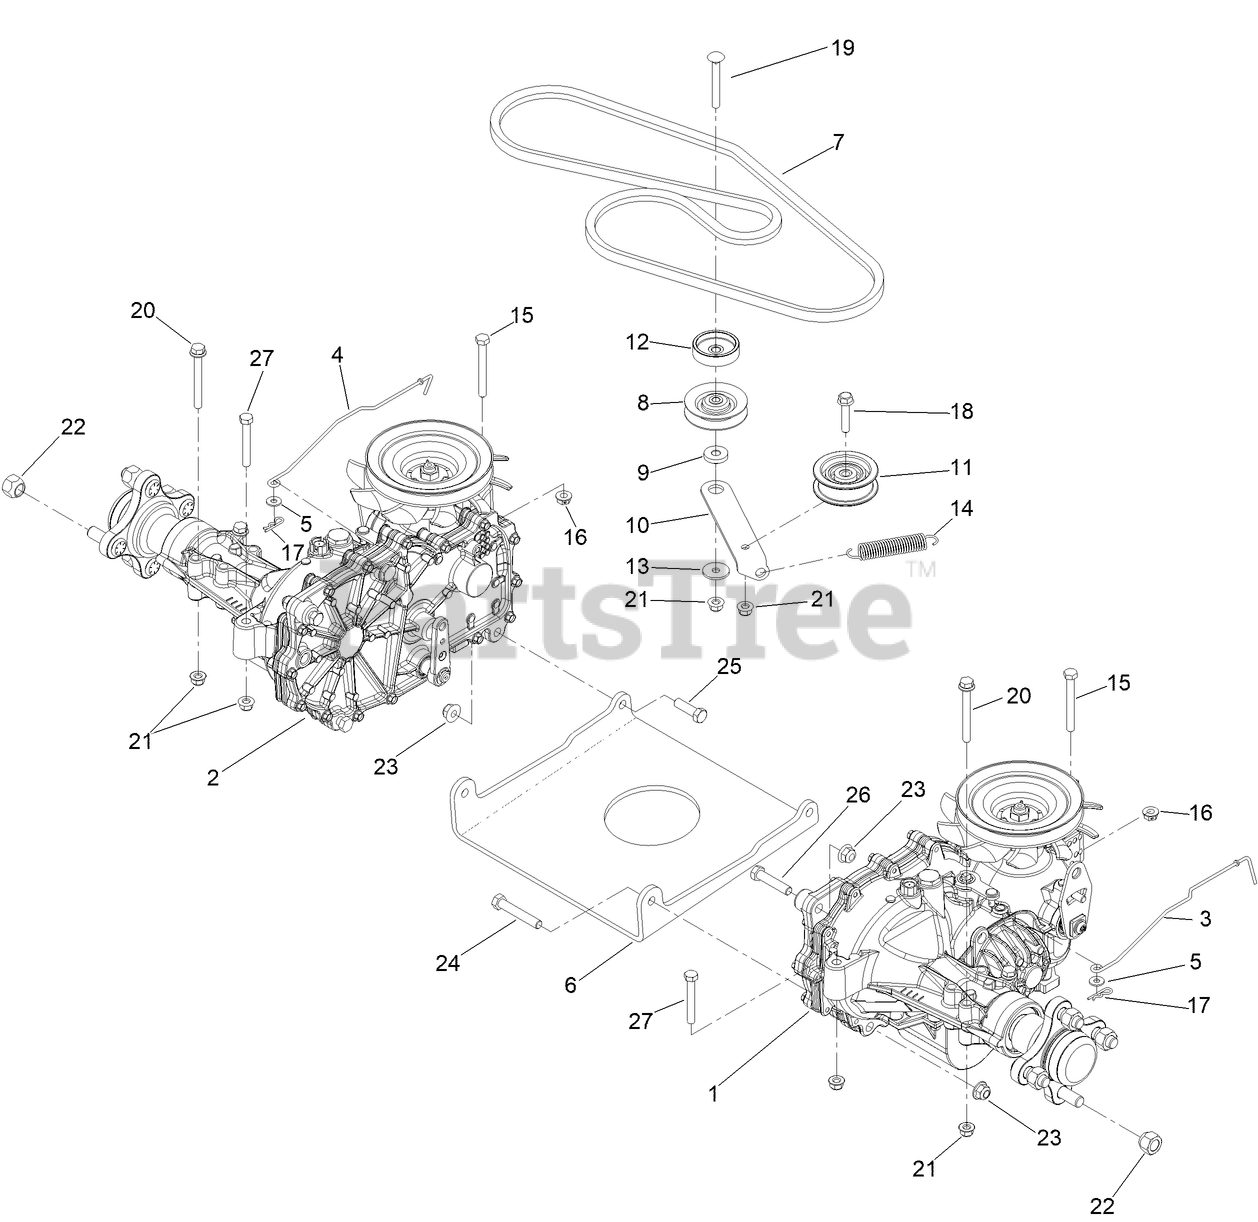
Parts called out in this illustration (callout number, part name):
1	LH HYDRO TRANSMISSION ASM
2	RH HYDRO TRANSMISSION ASM
3	ROD-BYPASS, LH
4	ROD-BYPASS, RH
5	WASHER
6	PLATE-HYDRO
7	V-BELT (A SEC 66.30 EL)
9	SPACER-IDLER ARM
10	ARM-IDLER
11	PULLEY-IDLER, FLAT
12	SPACER
13	WASHER-PIVOT
14	SPRING-PEDAL, RETURN
15	SCREW-HH SPCL
16	NUT-HF
18	SCREW-HHF
19	SCREW-CARR
20	SCREW-HHF
21	NUT-HF, NI
22	NUT-LUG
23	NUT-HF, NI
24	SCREW-HH
25	SCREW-HH
26	SCREW-HH
27	SCREW-HH
